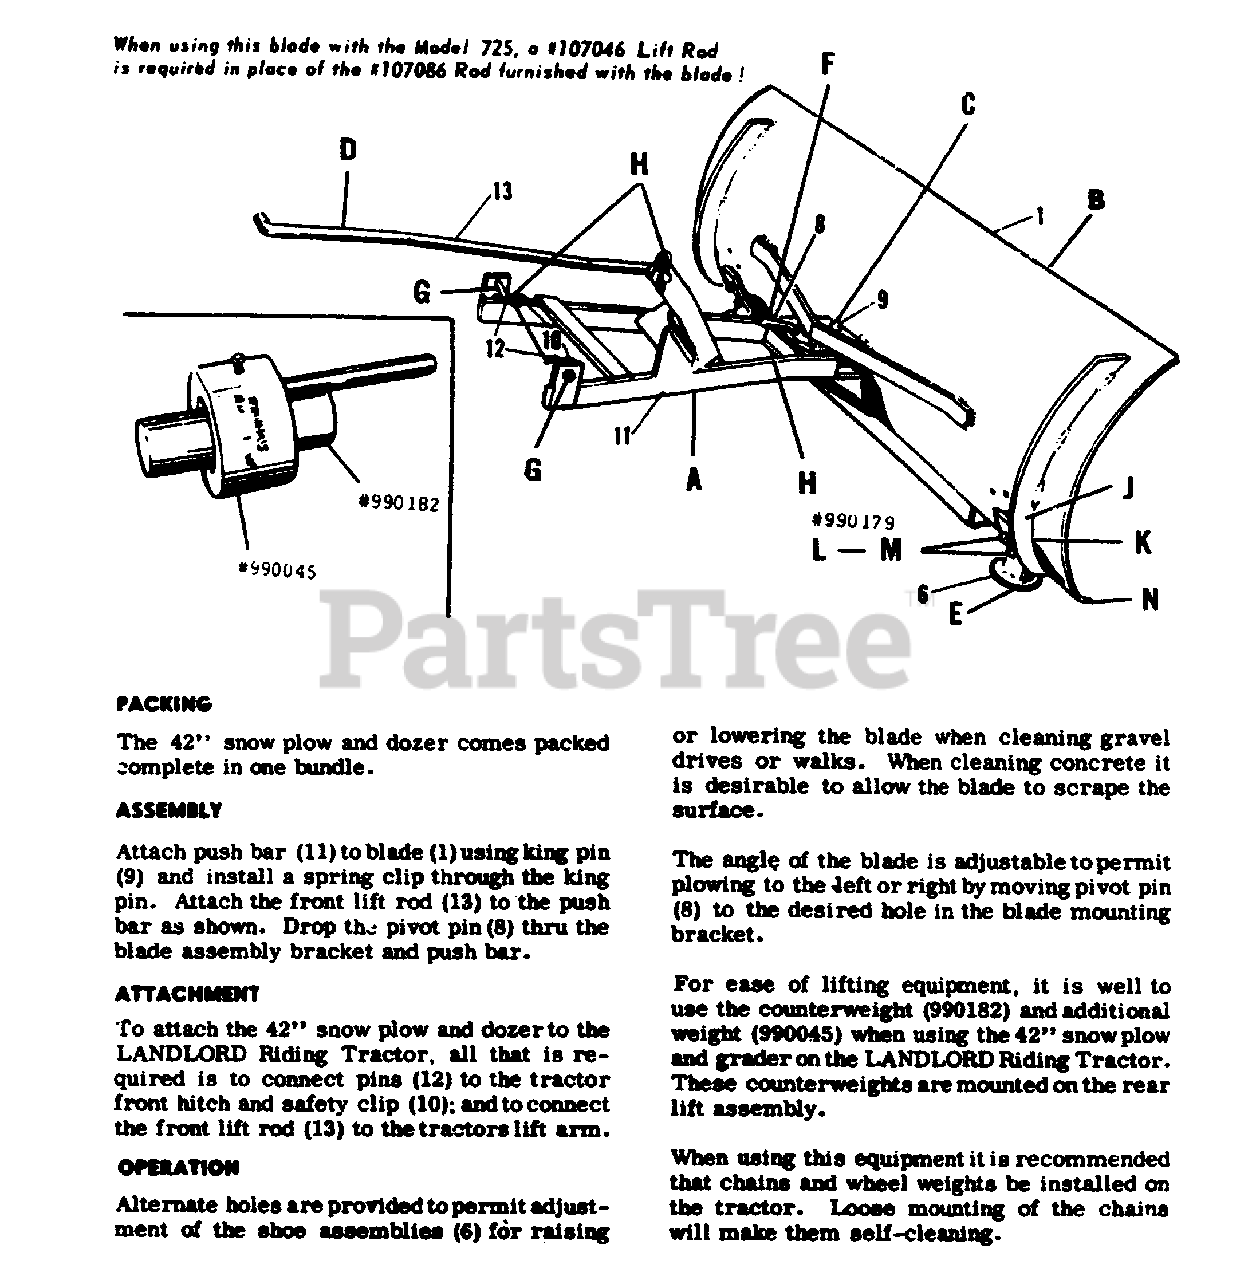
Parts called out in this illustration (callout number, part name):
A	Push Bar Assembly
B	Blade Assembly, 42"
C	Pin, King, 1/2" dia. x 2-1/2" lg.
D	Rod, Front Lift
E	Shoe Assembly
G	Pin
H	Clip, Spring
J	Bolt, Carriage, 3/8"-16 N.C. x 1" lg.
K	Bolt, Carriage, 3/8"-16 N.C. x 3/4" lg.
L	Washer, Lock, 3/8"
M	Nut, Hex., Full, 3/8"-16 N.C.
N	Plate, Wear
